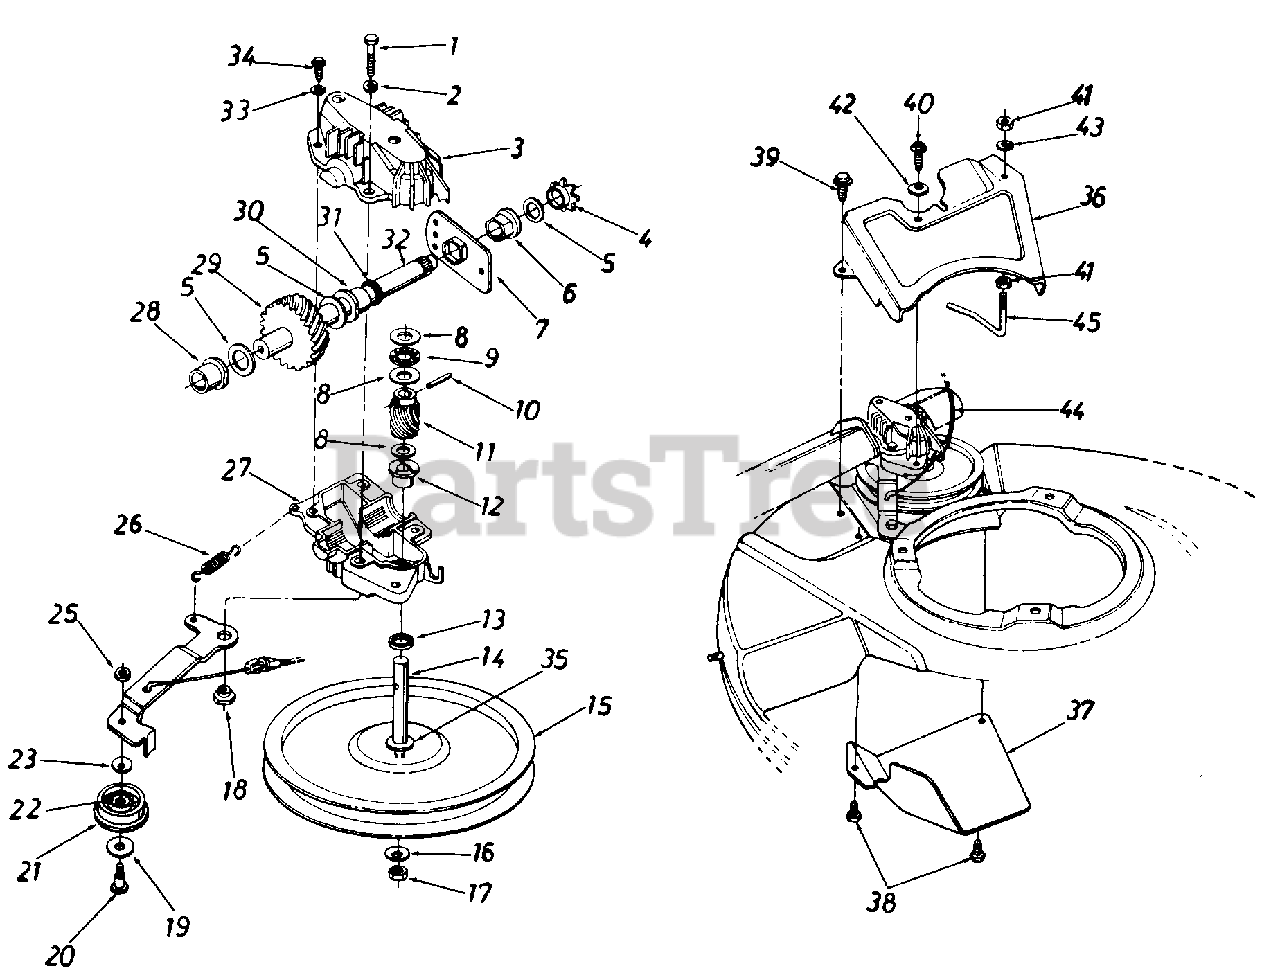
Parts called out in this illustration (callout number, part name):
1	Hex Bolt 1/4-20 x 1.25" Lg.
2	L-Wash. 1/4" l.D.
3	Upper Hsg. Half
4	#48 Sprocket 7 Tooth x 1/2 0 Pitch
5	Fl-Wash. 5/8" I.D. x .030
6	Hex Flange Brg. .631" I.D.
7	Hex Bearing Cup
8	Thrust Wash. .382" I.D. x .70" O.D.
9	Thrust Bearing .375" I.D. x .812" O.D.
10	Spring Pin Spir. 1/8" x .62" Heavy
11	11 Tooth Helical Gear
12	Flange Bearing
14	Pulley-Transmission Shaft
15	Fl-Pulley 5.06" O.D.
16	Bell-Wash. .265" I.D. x 75"
17	Hex L-Nut 1/4-28 Thd.
18	Shld. Spacer .375" Dia. x .170
19	Fl-Wash. .390" I.D. x 1.0"
20	Shld. Bolt .375" Dia. x .40"
21	Fl-ldler Plastic 1.50" Dia.
22	Needle Brg. 375" x .31
23	Bell-Wash. .265" I.D. x 75"
25	Hex Patch L-Nut 1/4-28 Thd.
26	Extension Spring 1.12" Lg.
27	Lower Hsg. Half
28	Flange Bearing .566 Dia.
29	33 Tooth Helical Gear
30	Flange Bearing .629 Dia.
31	Oil Seal .625 Dia.
32	Gear Sprocket Shaft
33	L-Wash. #10 I.D.
34	Hex B-Tap Scr. #10 x .62"
35	Hex Washer .26" x .88"
36	Transmission Belt Guard
39	Hex AB-Tap Scr. 1/4 x .50"
40	Hex B-Tap Scr 1/4 x 62" Lg
41	Hex Nut 1/4-20 Thd.*
42	Bell-Wash. .265" I.D. x 75"
43	L-Wash. 1/4" l.D.*
44	S.P. Cable 50n Lg
45	S.P. Belt Guard
